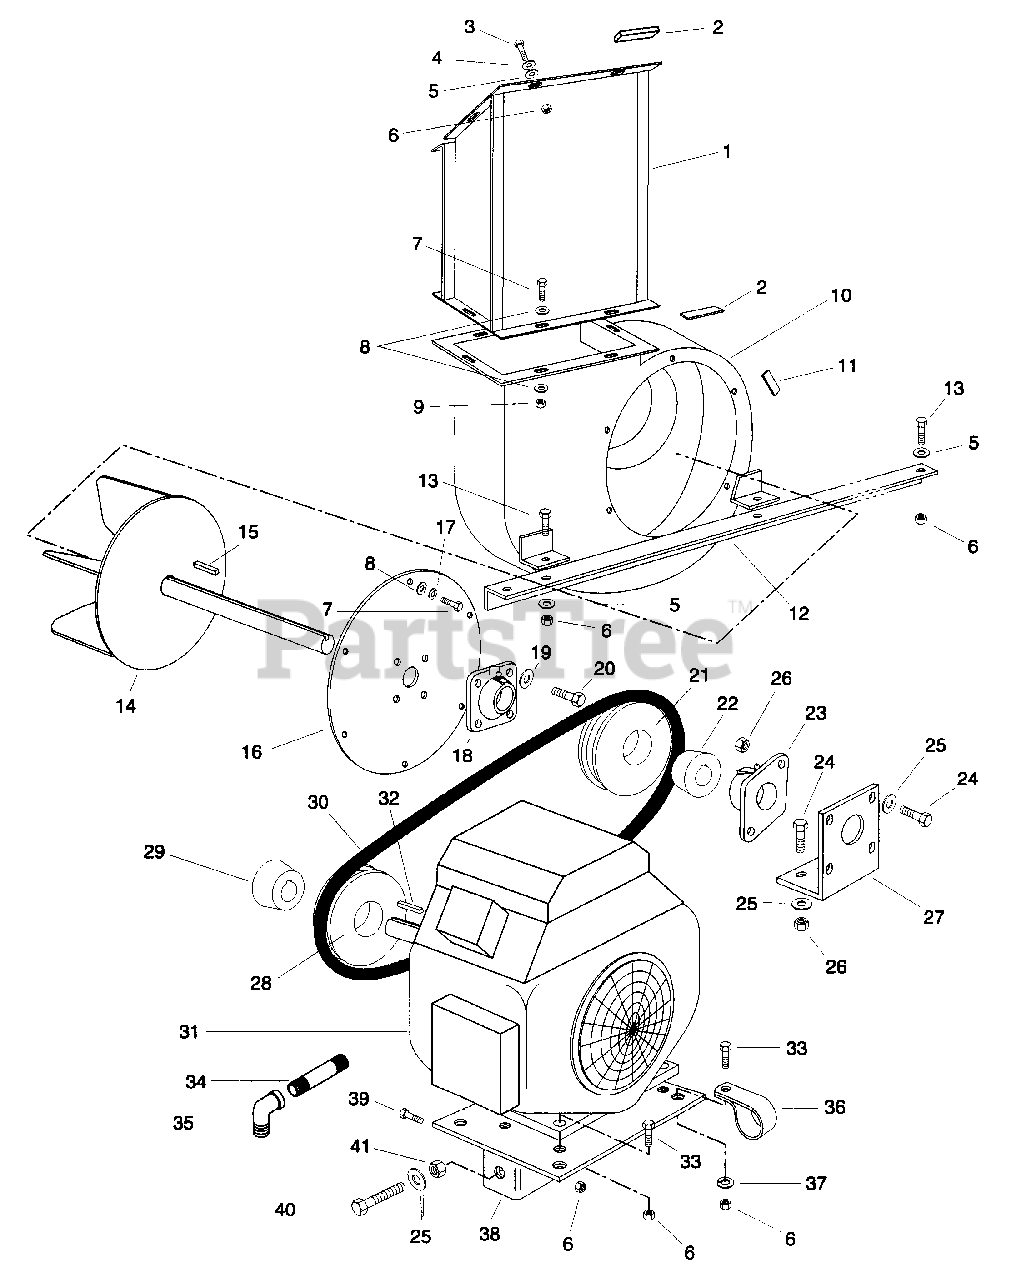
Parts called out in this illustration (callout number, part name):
1	Discharge Chute Weldment
3	Blt-Hex .38-16 x .75 Gr 5
4	Wshr-Fl-St I .511 x 1.441 x .125
5	Nut-Lk Top .375-16 Gr C Pl
6	Nut-Lk-Ctr .38-16
7	Blt-Hex .31-18x .75 Gr5
8	Wshr-Fl-Stl .38 x .875 x .083
9	Nut-Lk-Ctr 31-18
10	Blower Weldment
11	Gasket
12	Blower Support Beam
13	Blt-Hex .38-16 x 1.00 Gr 5
14	Fan
15	Key Str .38 x 2.0 x .38
16	Fan Cover Weldment
17	Wshr-Lock .31 x .078
19	Wshr-Lk .31 x .078
20	Blt-Hex .44-14 x 1.25 Gr 5
21	Pulley - V 2G 3V 6.5 Taper Lock
22	Driven Sheave Bushing
23	Bearing 2 Bolt
24	Blt-Hex .50-13 x 1.50 Gr 5
25	Wshr-Fl-Stl .563 x 1.38 x .109
26	Nut-Lk-Ctr .50-13
27	Bearing Holder
28	Pulley - V 2G 3V 5.5 Taper Lock
29	Drive Sheave Bushing
30	V-Belt Matched Set of Two
31	Engine-18 HP Kohler Command
32	Key-Sq .25 x 1.25 x .25 SAE
33	Blt-Hex .38-16 x 3.00 Gr 5
34	Nipple
35	Elbow .375-18
37	Wshr-Fl-Stl .438 x 1.00 x .083
38	Engine Base Weldment
39	Blt-Hex .38-16 x 1.25 Gr 5
40	Blt-Hex .50-13 x 5.00 Gr 5
41	Nut-Hex .50-13
